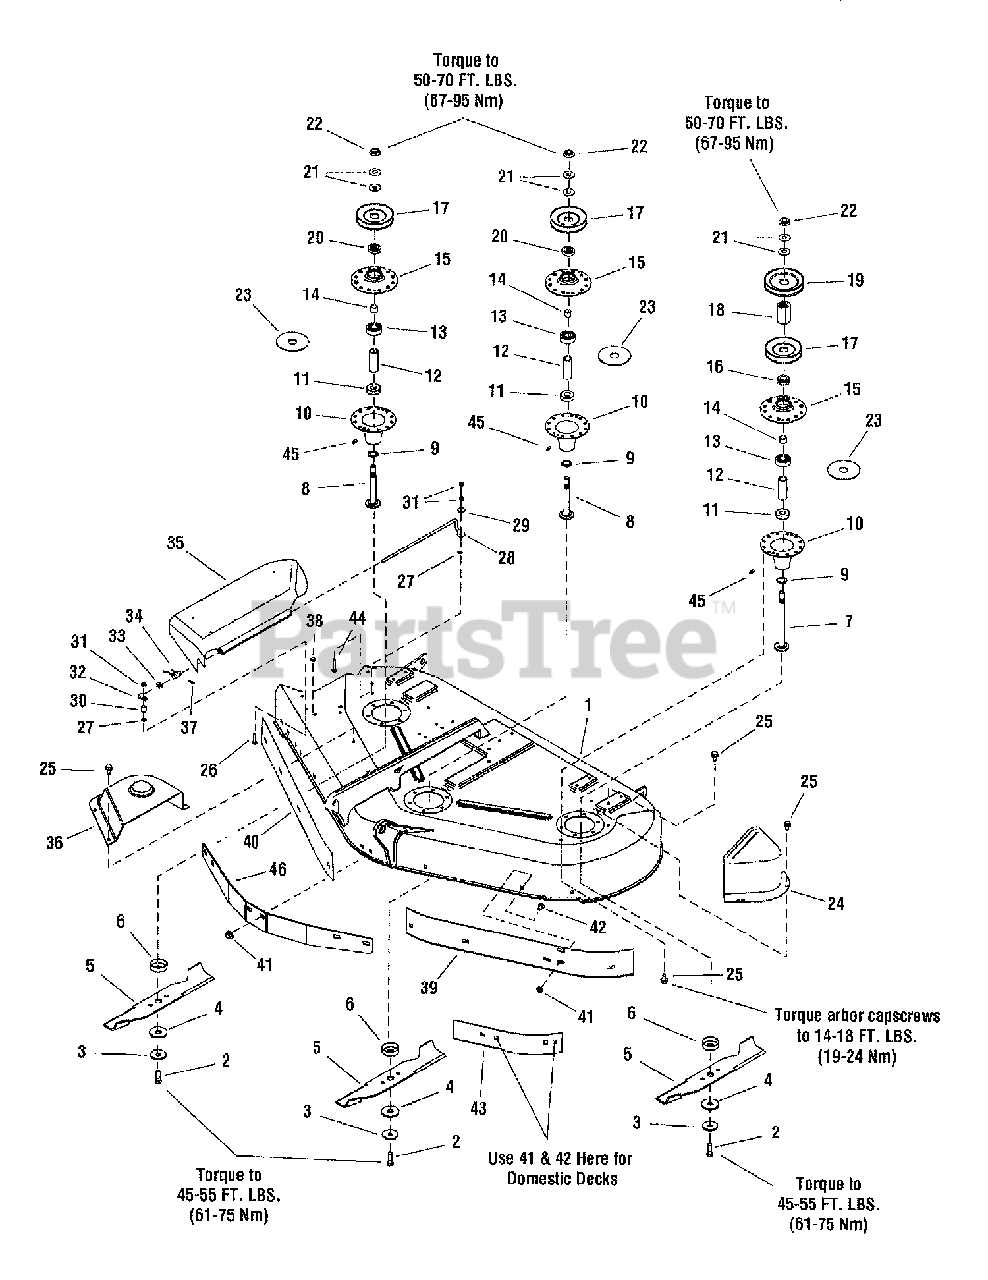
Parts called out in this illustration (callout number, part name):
1	HOUSING ASSY, 50"
2	CAPSCREW, Hex 7/16-14 x 1-1/4
3	WASHER, Spring
4	WASHER, Hex, 11/16 x 2
5	BLADE, Mower 18.13" LG
6	SHIELD, Grass Lower Arbor
7	SHAFT, Arbor
8	SHAFT, Arbor
9	WASHER
10	HOUSING, Arbor Bottom (includes ref 45)
11	BEARING
12	SPACER, 2.679
13	BEARING
14	SPACER, Bearing Sleeve
15	HOUSING, Arbor Top
16	HUB, Pulley Double
17	PULLEY
18	HUB, Pulley Double
19	PULLEY
20	HUB,PULLEY
21	WASHER, Bellville, 9/16
22	NUT, Hex Flange 9/16-18
23	GASKET, Foam
24	COVER, Arbor
25	SCREW, Hex Washer, Taptite 5/16-18 x 3/4
26	BOLT, Carriage 1/4-20 x 1-1/4
27	NUT, Push On
28	ROD, Deflector Front
29	WASHER
30	SPACER, 5/8
31	NUT, Hex Lock ESNA LIGHT 1/4-20
32	CLAMP
33	WASHER, Plain
34	SPRING
35	DEFLECTOR
36	COVER, Arbor
37	CAP, Spring End
38	PLUG, Hole
39	BAFFLE, Blowout, 50" LH
40	BAFFLE, Blowout, 50" RH
41	NUT, Hex Flange 5/16-18
42	BOLT, Carriage 5/16-18 x 3/4
43	BAFFLE, Front LH
44	BOLT, Carriage 1/4-20 x 1-1/2
45	FITTING, Grease
46	BAFFLE, Anti-Blowout
